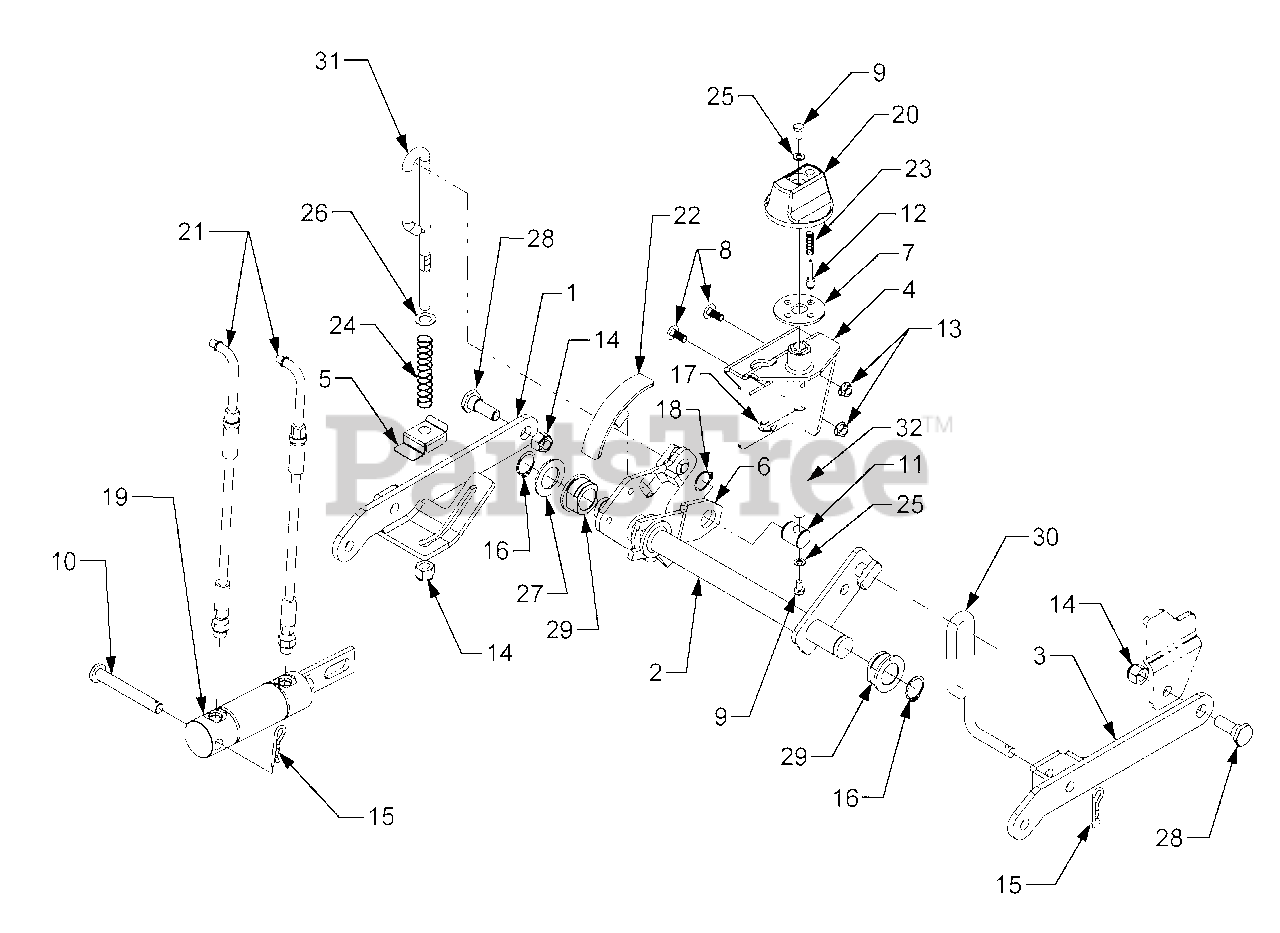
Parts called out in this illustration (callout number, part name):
1	Link, LH Lift
4	Bracket, Downstop
5	Stop Bracket, Lift Rod
6	Arm, Downstop
7	Disk, Detent
8	Bolt, Carriage, 3/8-16 x .75
9	Screw, Hex Cap, 1/4-20 x .5 GR5
10	Pin, Clevis, .5 x 3.75
11	Ferrule, Adjustment
12	Pin, Detent Plunger
13	Nut, Flange Lock, 3/8-16 GR5
14	Nut, Hex Lock, 1/2-13
15	Pin, Internal Cotter
16	Snap Ring, 1.0 Dia. Shaft
17	Ring, 'E' Retaining, .5 Dia.
18	Snap Ring, .875 Dia. Shaft
19	Cylinder, Center Lift
20	Knob
21	Hose, Lift
22	Indicator, Lift Position
23	Spring, Compression
24	Spring, Compression
25	Washer, Flat, .281 x .5 x .063
26	Washer, Flat, .536 x .93 x .050
27	Washer. Flat, 1.0 x 1.7 x .10
28	Shoulder Screw
29	Bearing, Flange w/Flats
30	Rod, RH Lift
31	Rod, LH Lift
32	Screw, Adjustment
